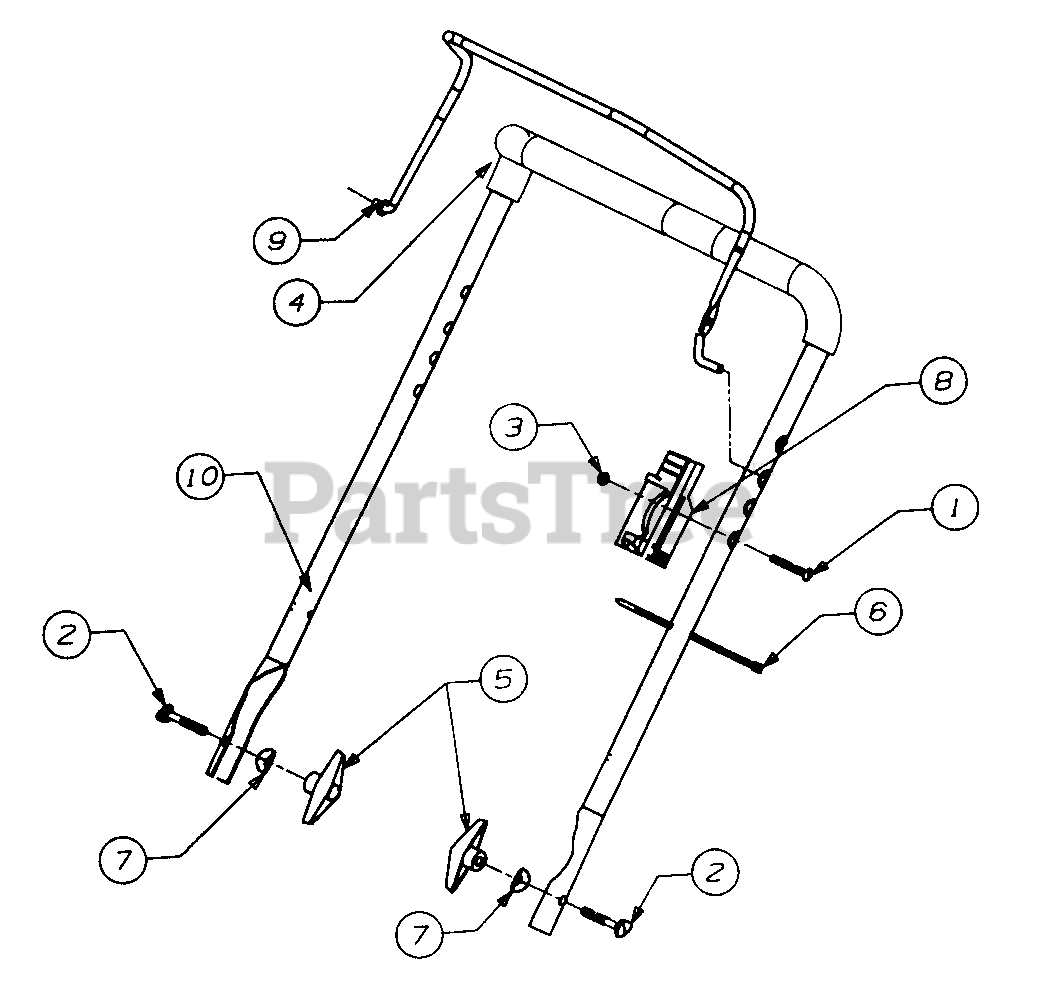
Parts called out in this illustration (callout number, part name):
1	Screw - Oval C-Sink L
2	Bolt - Carriage
3	Nut Insul. Lock
4	Grip Foam
5	Knob Handle
6	Tie Cable
7	Washer Saddle
8	Body - Lever Control
